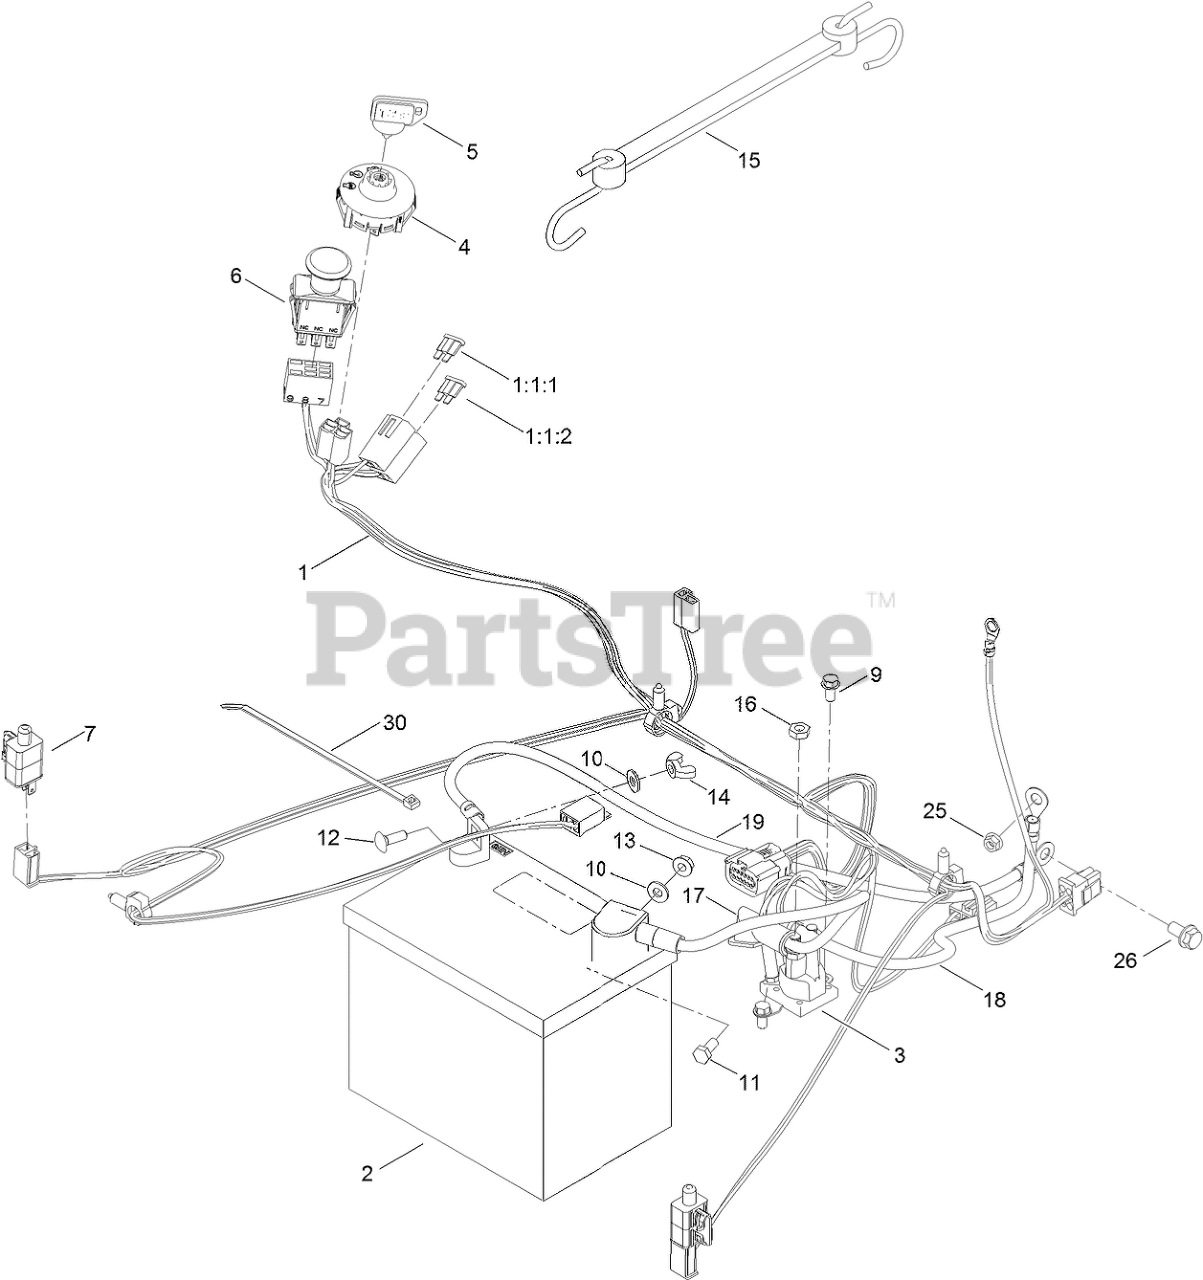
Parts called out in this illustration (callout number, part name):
1	HARNESS-WIRE
1:1:1	FUSE-BLADE, 30 AMP
1:1:2	FUSE-BLADE, 25 AMP
2	BATTERY
3	SOLENOID
4	SWITCH-IGNITION
5	KEY-IGNITION
6	SWITCH-PTO
7	SWITCH
9	SCREW-HWH
10	WASHER-FLAT
11	SCREW-HH
12	BOLT-CARR
13	NUT-HF
14	NUT-WING
15	HOLDDOWN-BATTERY
16	NUT-JAM
17	CABLE-BATTERY, RED
18	CABLE-BATTERY, POSITIVE
19	CABLE-BATTERY, BLACK
25	NUT-HF
26	SCREW-HHF
30	TIE-CABLE
